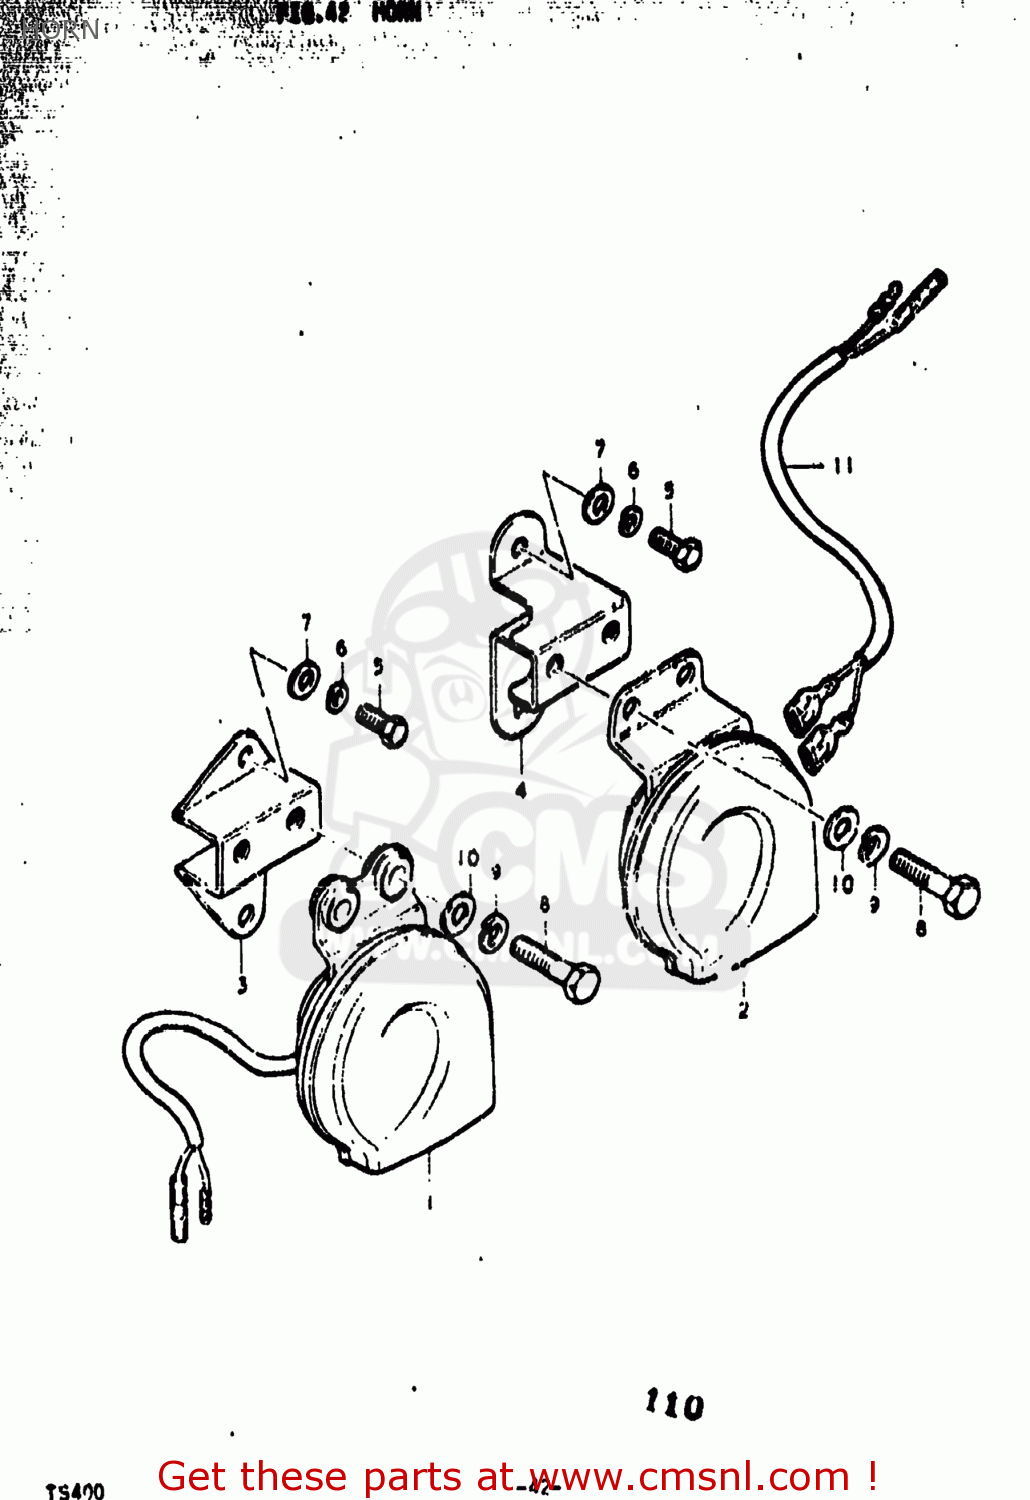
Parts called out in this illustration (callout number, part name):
1	HORN ASSEMBLY
2	HORN ASSEMBLY
3	BRACKET,HORN
4	BRACKET,HORN
5	SCREW 6X12
6	LOCK WASHER
7	WASHER
8	BOLT
9	LOCK WASHER
10	WASHER
11	WIRE,HORN LEAD
